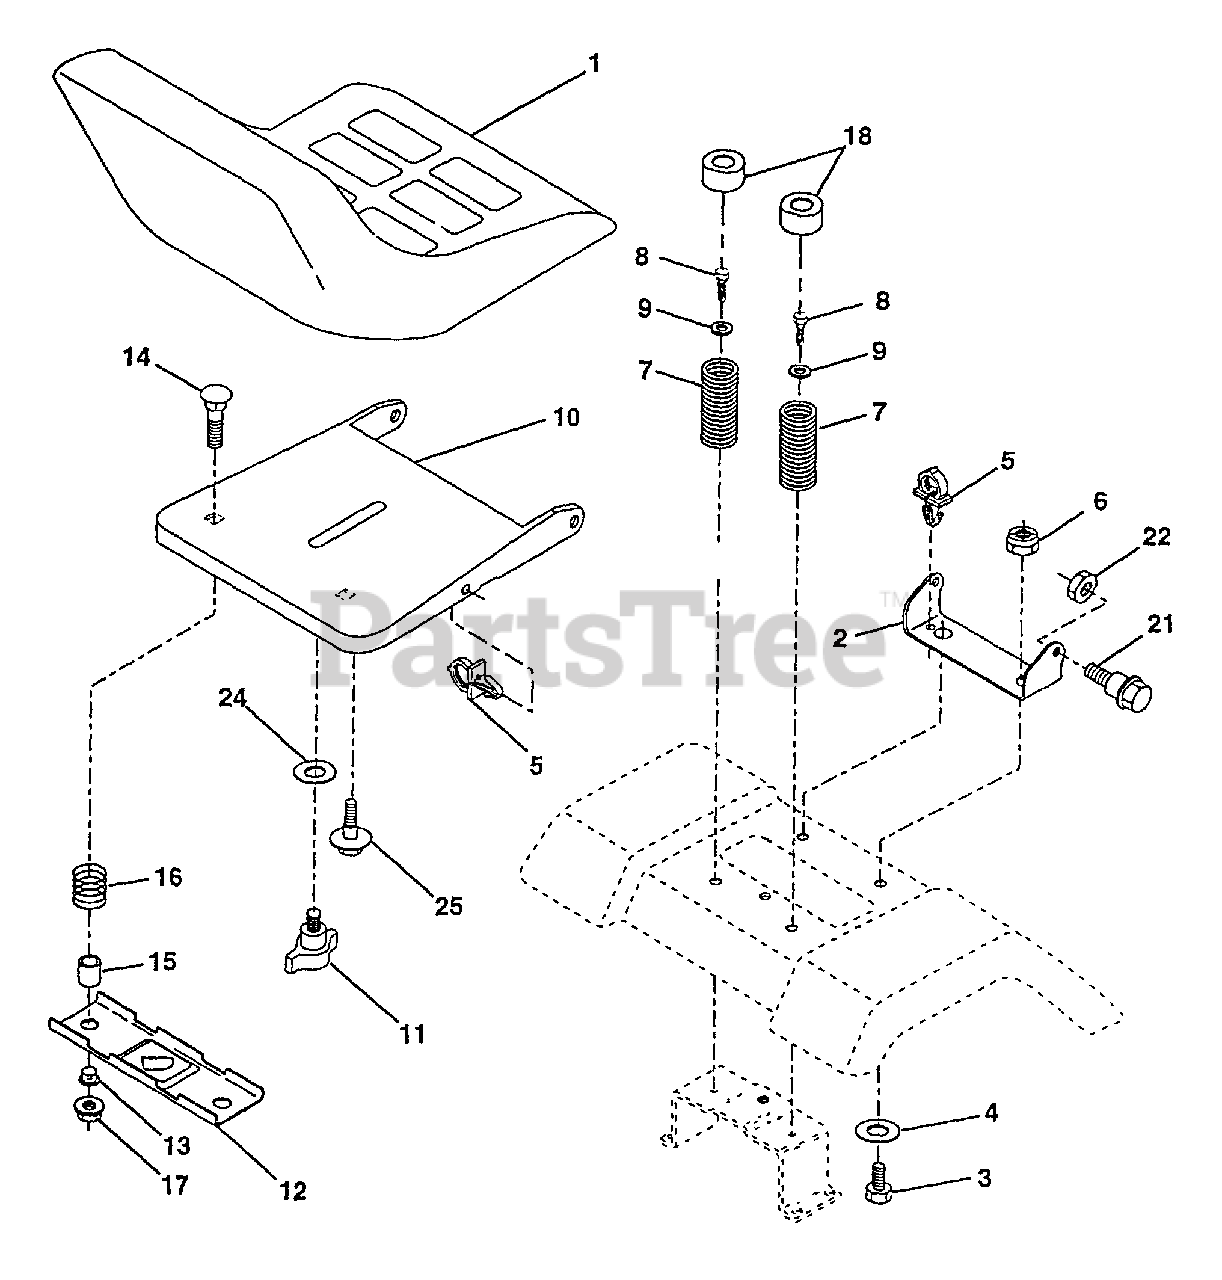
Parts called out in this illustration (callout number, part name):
2	Bracket Pivot Seat 8 720
3	Bolt Fin Hex 3/8-16unc X 1
4	Washer 13/32 X 1 X 10 Ga
5	Clip Push-In
6	Nut Hex w/Ins. 3/8-16 Unc
7	Spring Seat Cprsn 2 250 Blk Zi
8	Screw Thdrol 3/8-16 X 1 Ty-tt
9	Washer 13/32 X 1 X 14 Ga. (AYP part number)
10	Pan Seat (AYP part number)
11	Knob Seat Adj. Wingnut
12	Bracket Mounting Switch
13	Bushing Snap Blk Nyl 50 Id
14	Bolt Rdhd Sqnk 1/4-20x1-1/2
15	Spacer Split 28x 88
16	Spring Cprsn
17	Nut Lock 1/4 Lge Flg Gr 5 Zinc (AYP part number)
18	Cap Spring Seat Blk
21	Bolt Shoulder 5/16-18 Unc (AYP part number)
22	Nut Hex Lock W/Ins 5/16-18
24	Washer 17/32 X 1-3/16 X 12 Ga.
25	Bolt Shoulder 5/16-18 X 62
